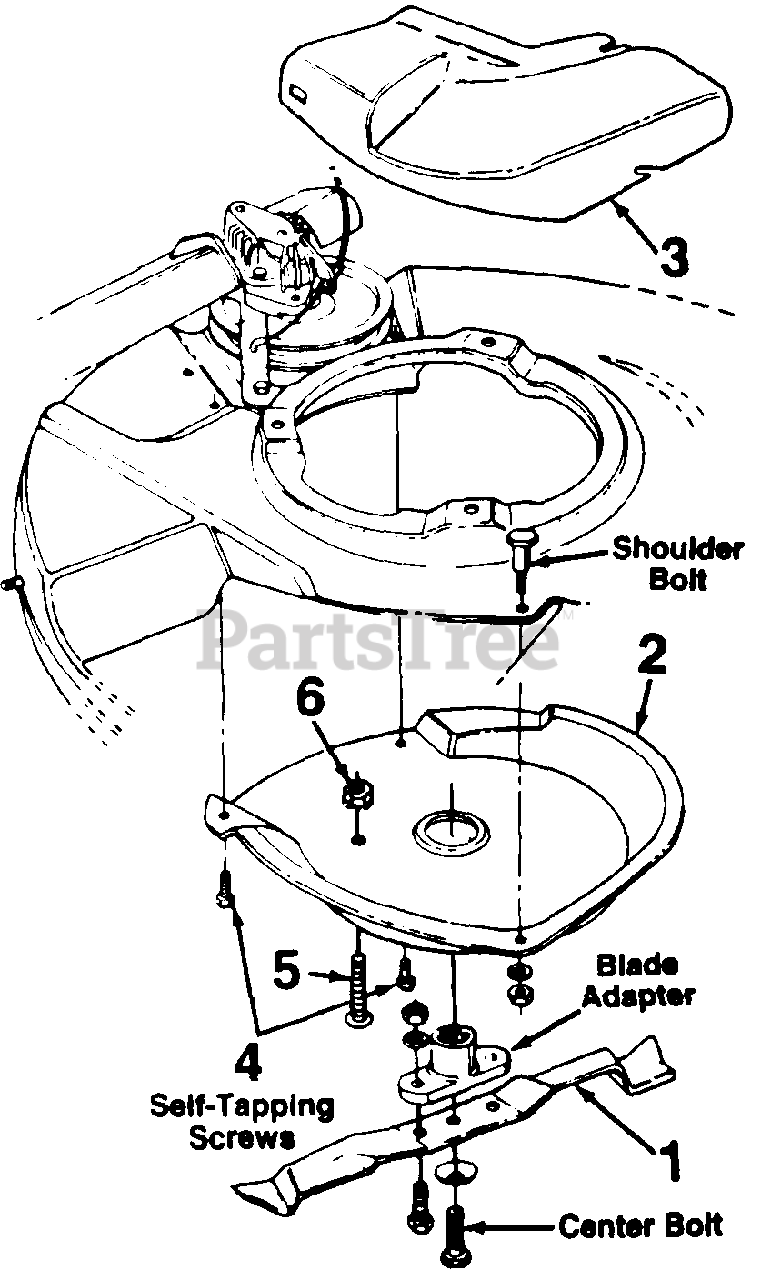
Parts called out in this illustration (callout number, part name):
1	Mulching Blade
2	Mulching Baffle
3	Mulching Plug
4	Self-Tapping Screw
5	Phillips Scr. 1/4-20 x 1.5" Lg.
6	Hex Sems Nut 1/4-20 Thd.
